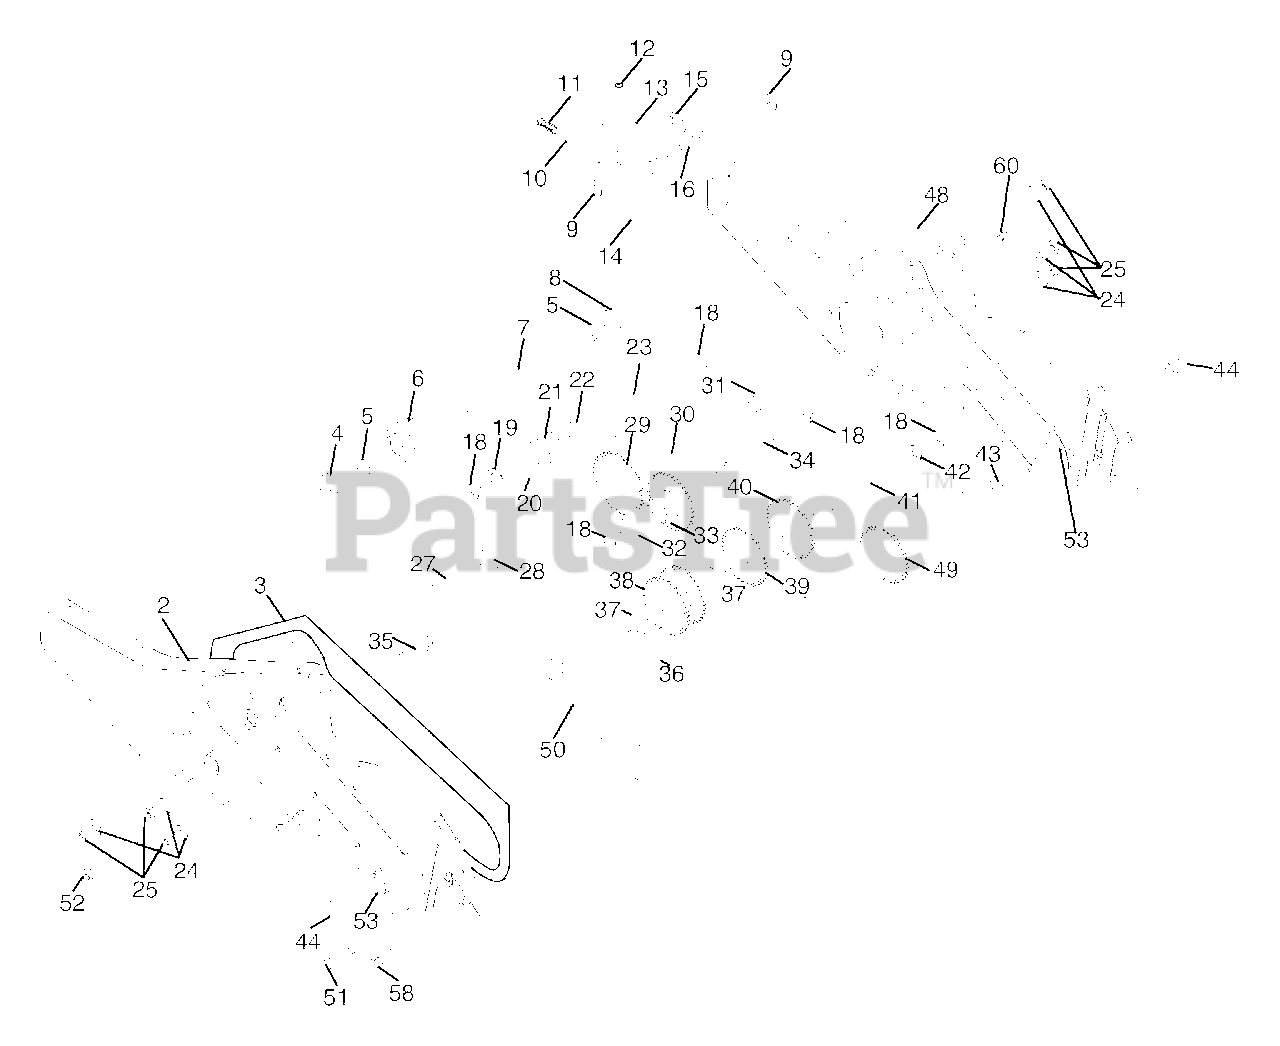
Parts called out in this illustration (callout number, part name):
1	Transmission Assembly
2	Gearcase, L.H. w/Bearing
3	Gasket, Gearcase
4	Bearing, Needle
5	Washer, Thrust 5/8 x 1.10 x 1/32
6	Pinion, Input
7	Shaft, Input
8	Bearing, Needle
9	Washer, Seal
10	Ball, Steel
11	Spring, Shift, Fork
12	O-Ring
13	Bracket, Shift
14	Fork, Shift
15	Ring, Klip
16	Shaft, Shift
18	Washer
19	Ring, Klip
20	Gear, Assembly, Reverse Idler
21	Gear, Reverse Idler
22	Bearing, Needle
23	Shaft, Reverse Idler
24	Washer, Lock 7/16
25	Nut, Hex 7/16-20
27	Bearing, Shaft, Ground Drive L.H.
28	Spacer 0.765 x 1.125 x 1.23
29	Chain #35-50 Pitch
30	Ground Shaft Assembly
31	Bearing, Shaft, Ground Drive R.H.
32	Spacer 0.70 x 1.00 x 1.150
33	Sprocket and Gear Assembly
34	Shaft, Reduction (2nd)
35	Screw, Whiz, Lock 5/16-18 x 3-1/2
36	Sprocket Assembly w/Bearing
37	Bearing, Needle
38	Sprocket, Tine
39	Gear, Cluster, Red 1st & 2nd
40	Gear, Reverse
41	Shaft, Reduction (1st)
42	Washer, Thrust
43	Spacer 1.01 x 1.75 x 0.760
44	Seal, Asm. Oil
48	Gearcase, R.H. w/Bearing
49	Shaft, Tine
50	Chain, Roller #50-50 Pitch
51	Screw 1/4-20 x 1/2
52	Nut, Hex 5/16-18
53	Kit, Bearing, Tine Shaft
58	Bolt Shoulder 1/4-20 x .875
60	Fitting Grease
